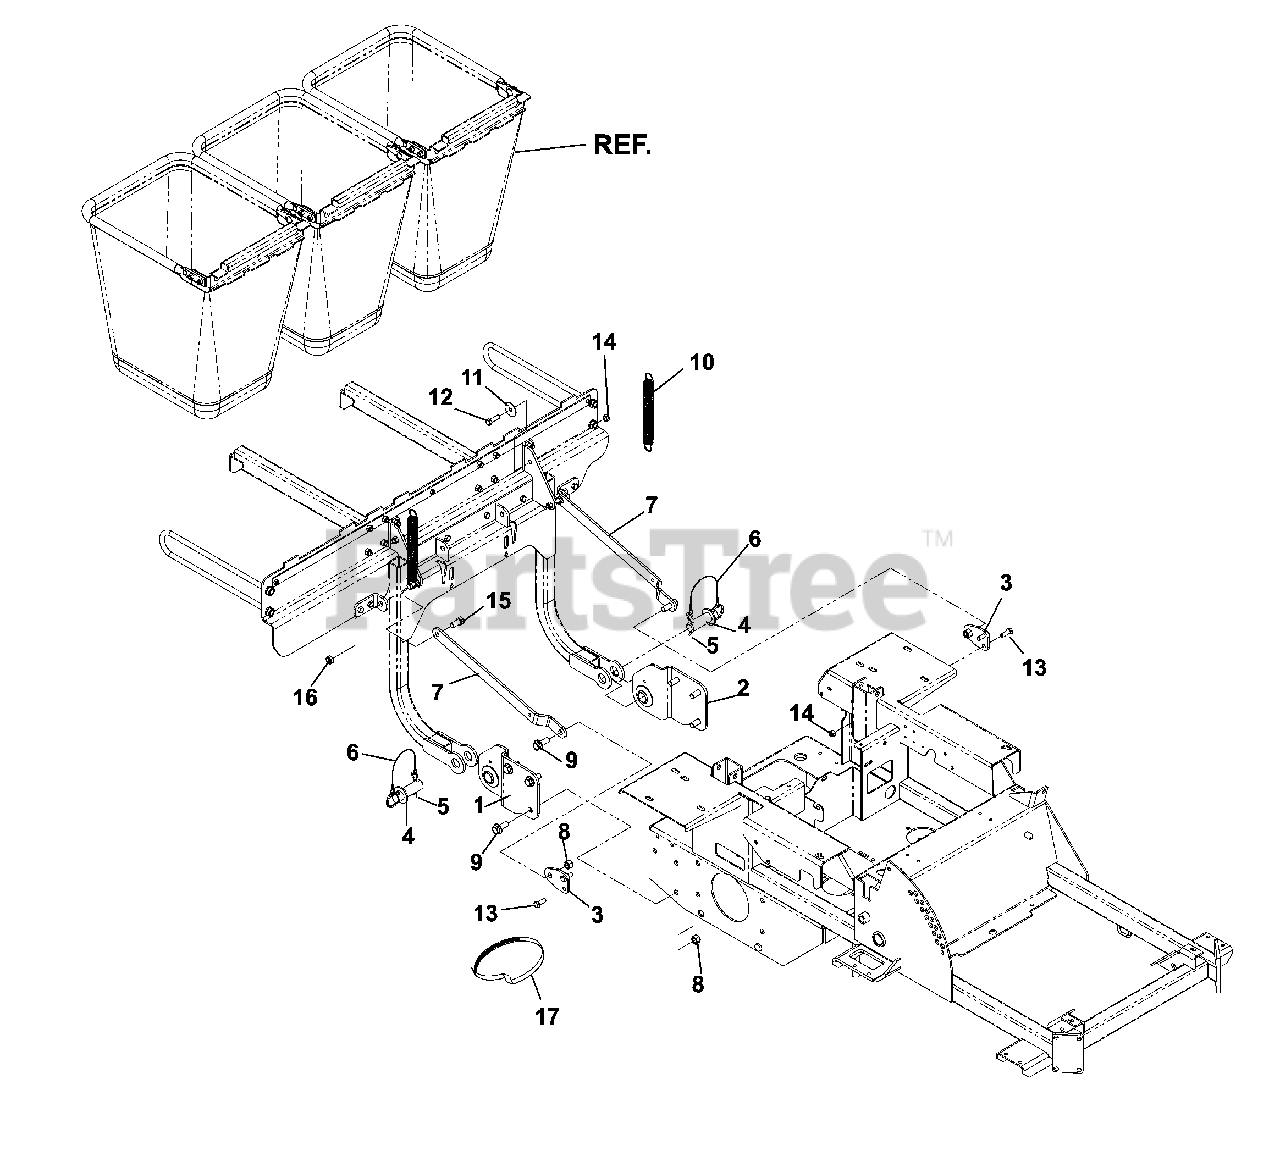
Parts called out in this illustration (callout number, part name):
1	HITCH BRACKET WLDMT, RT, MID
2	HITCH BRACKET WLD
3	SUPPORT BRACKET
4	HITCH PIN
5	HAIRPIN
6	LANYARD
8	NUT 1/2-13 HEX NYLOC ZD
9	HCS 1/2C X 1 1/4 SERRATED HEAD
11	WASHER, FRICTION
12	HCS 3/8C X 1 1/4 GR5
13	HCS 3/8C X 1
14	NUT 3/8-16 NYLOC
15	HHCS 1/2-13 X 1
16	NUT, 1/2-13 THIN PROF NYL
17	HOSE CLAMP
